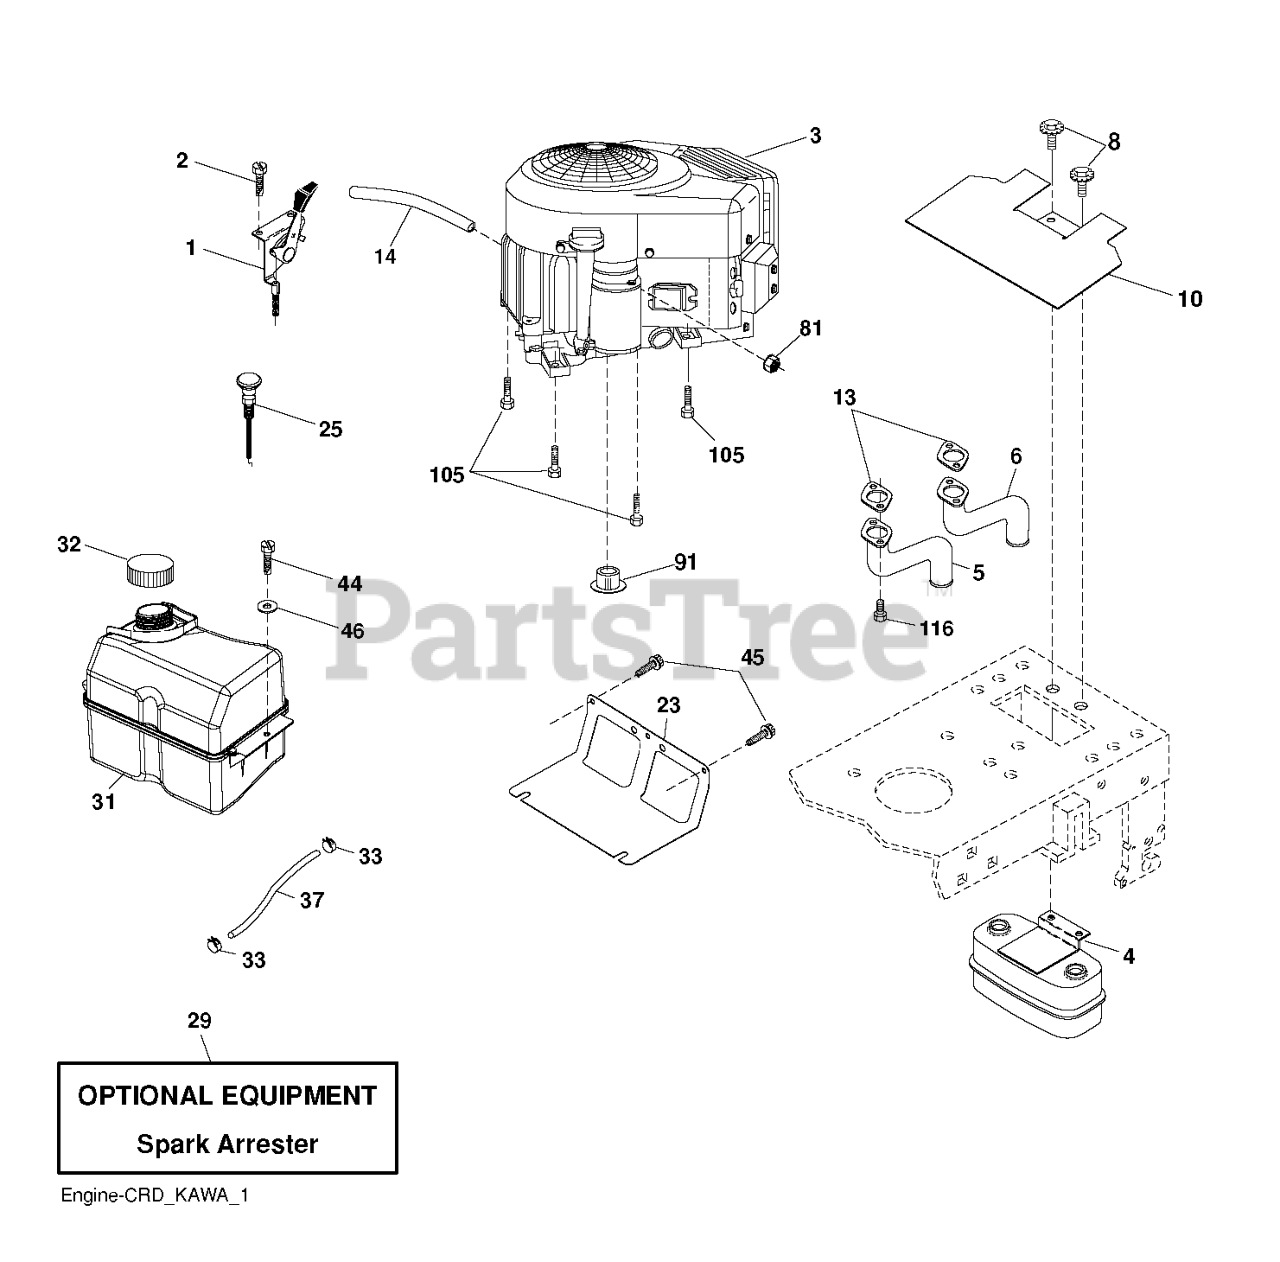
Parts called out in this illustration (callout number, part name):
1	CONTROL.THROTTLE.COBRA.BLACK
2	SCREW.#10 X 0.750.BOS
4	MUFFLER.TWIN.CYL.LOW.TONE
5	EXHAUST TUBE LH KAWI
6	EXHAUST TUBE RH KAWI
8	BOLT.5/16-18UNCX3/4 W/SEMS.BLK
10	RP SHIELD HEAT MUFFLER
13	GASKET.EXHAUST.KAWASAKI.15-1
14	TUBE, DRAIN OIL ASM.
23	SHIELD.BROWNING.DBR.GUARD
25	CONTROL.CHOKE.ERGO.PUSH-IN.BLA
29	KIT.SPARK ARRESTOR 794945 B&S
31	RP TANK FUEL FRT 1.5 GAL
32	CAP.FUEL.2.25"VENTED"
33	HOSE CLAMP
37	LINE.FUEL.20
44	SCREW HEXWSHR 1/4-20X3/4
45	SCREW, 3/8-16X3/4
81	NUT
91	BUSHING.1.375OD
105	SCREW 3/8-16X1
116	NUT.HEX.FLANGE.TOPLOCK
